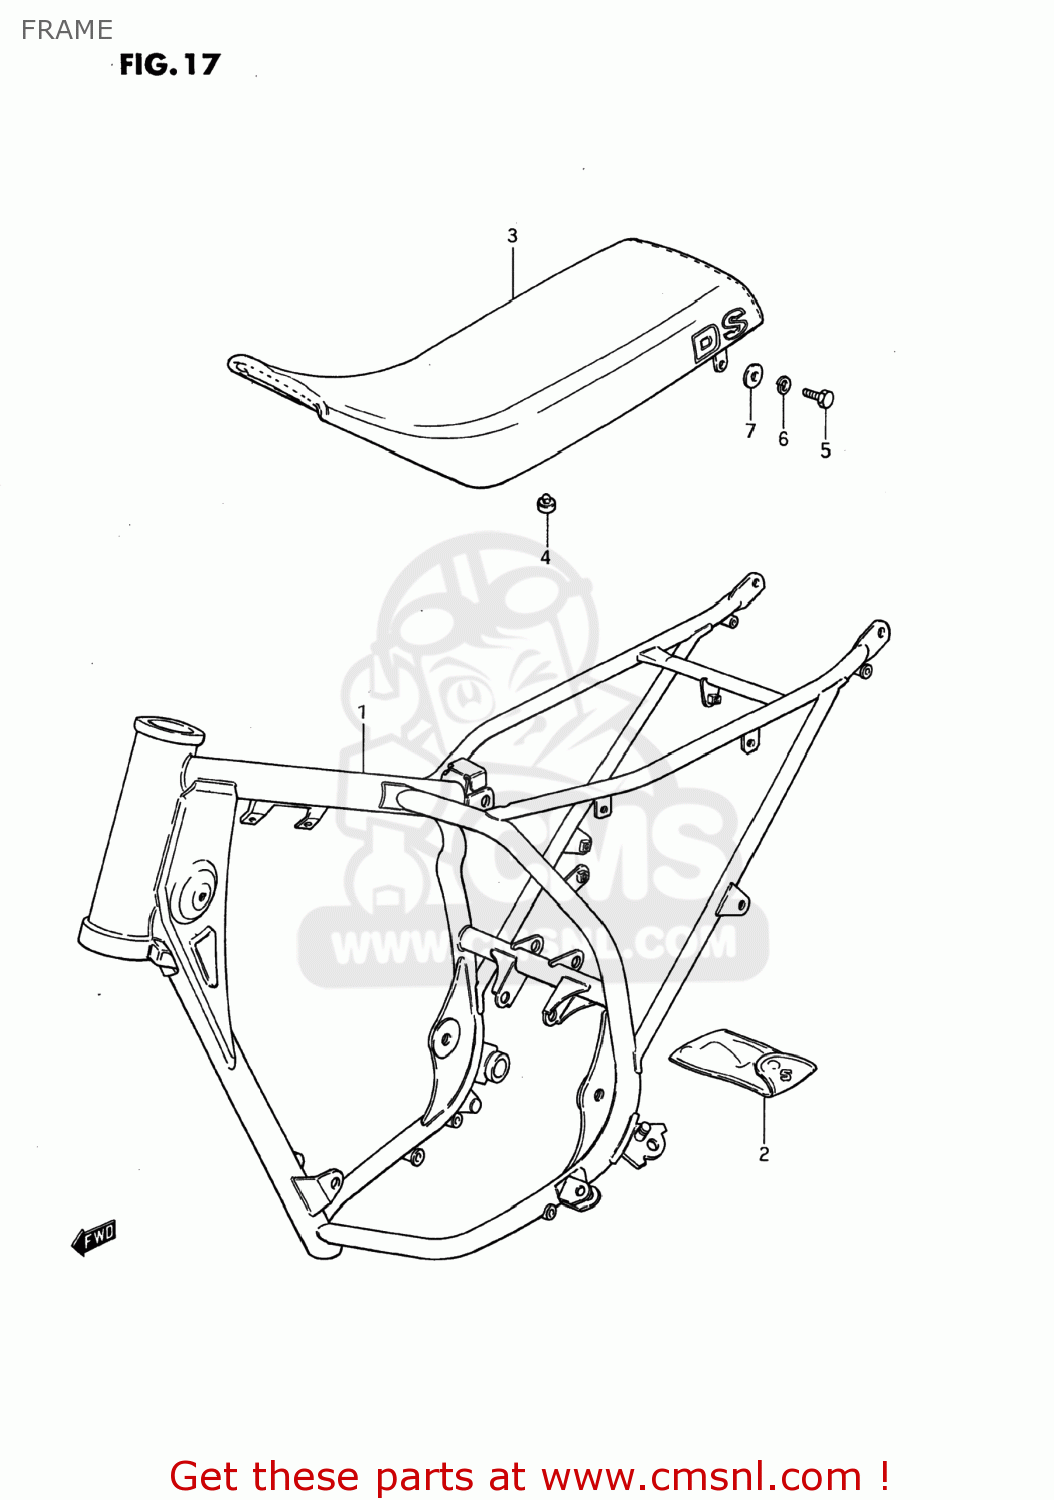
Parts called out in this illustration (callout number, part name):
1	FRAME
2	TOOL ASSY
3	SEAT ASSEMBLY
4	CUSHION
5	BOLT
6	WASHER,LOCK
7	WASHER (6.5X18X1.6)
